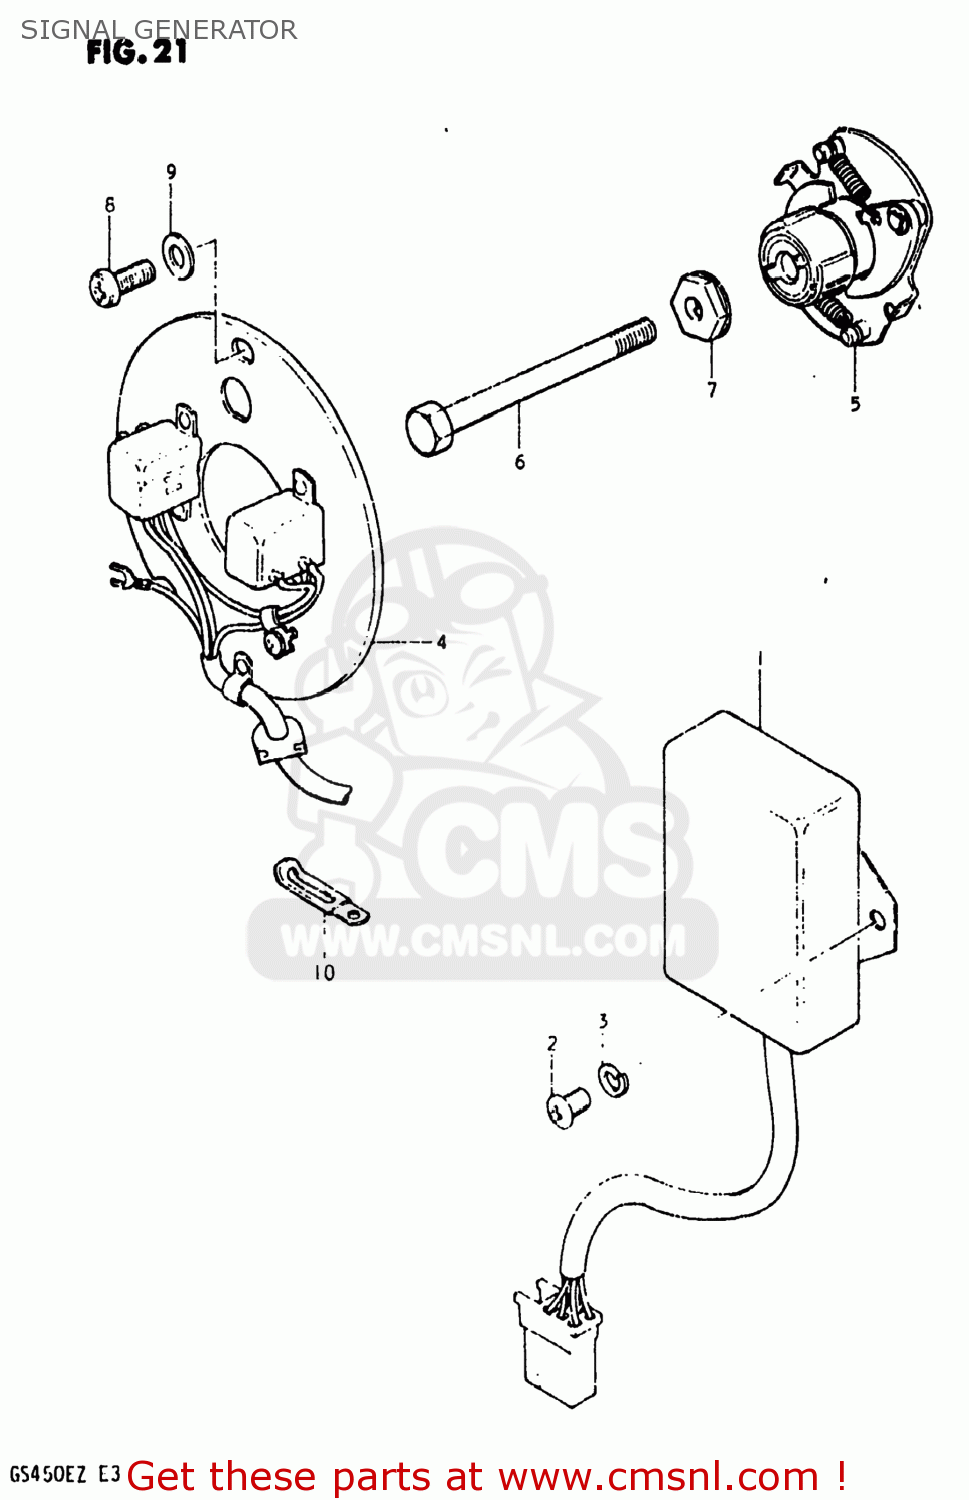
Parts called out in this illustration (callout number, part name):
1	CDI UNIT KOKUSAN
2	SCREW
3	LOCK WASHER
4	SIGNAL GENERATOR ASSEMBLY
5	GOVERNOR ASSEMBLY
6	BOLT 6X60
7	WASHER,CONTACT BREAKER
8	SCREW(5X12)
9	WASHER
10	CLAMP L:35
